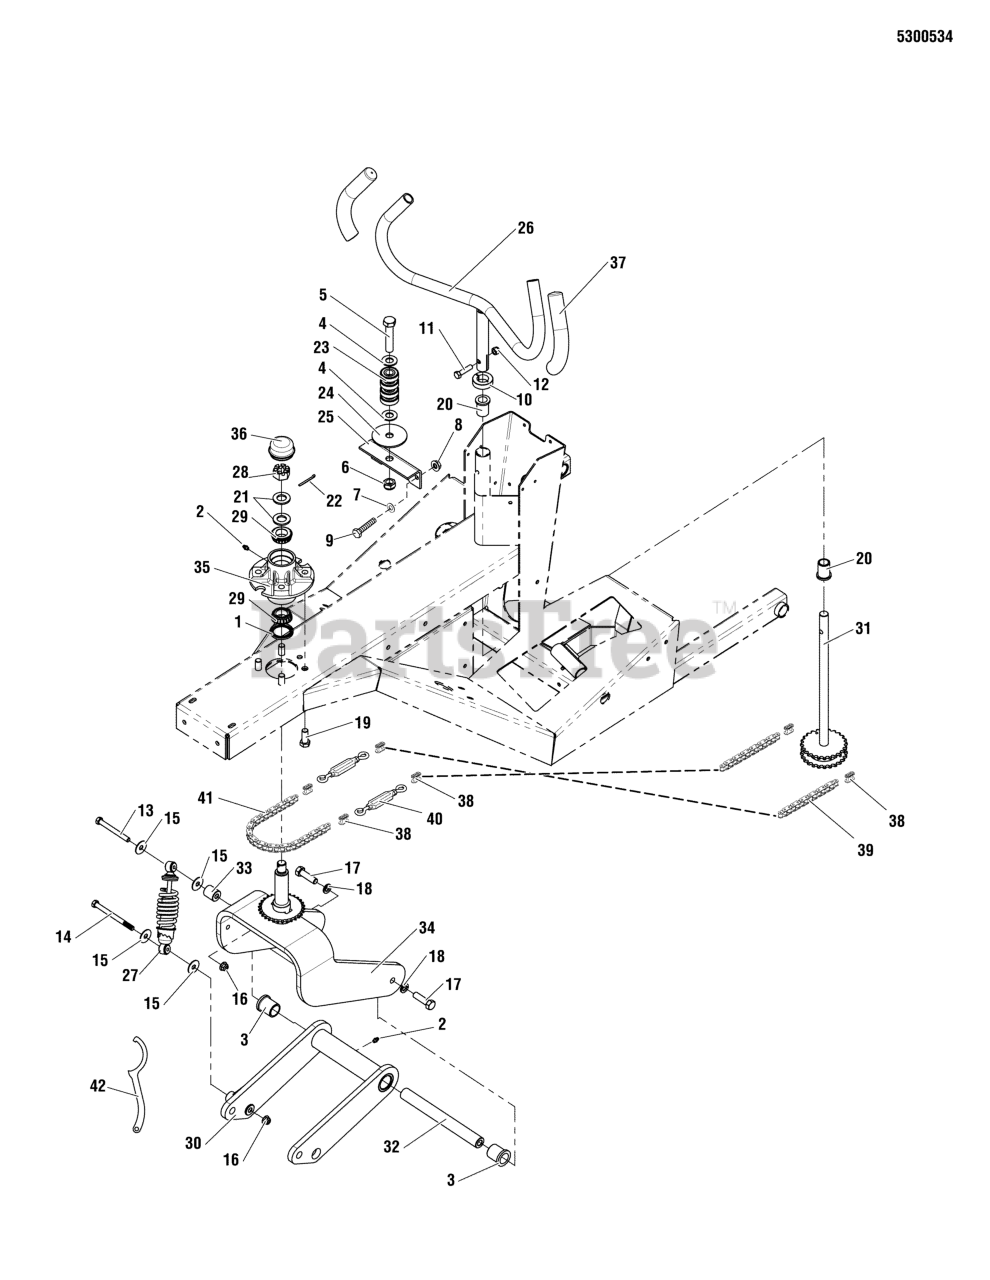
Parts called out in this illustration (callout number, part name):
1	SEAL, 1.983" X 1.500 X .188
2	GREASE FITTING, 1/4-28 STRAIGHT
3	BUSHING, FLANGE
4	WASHER, 5/8" SAE
5	BOLT, 5/8-11 x 3" GD5 CZ
6	NUT, 5/8-11 HEX JAM NYLON LOCK
7	WASHER, 5/16" SAE
8	NUT, 5/16-18 HEX NYLOCK FLANGE
9	BOLT, 5/16-18 X 3/4 GD5
10	COLLAR, 1" SPLIT
11	BOLT, 3/8-16 X 1-1/2" GD5 CZ
12	NUT, 3/8-16 HEX NYLON LOCK
13	BOLT, 3/8-16 X 3-1/2" GD5 CZ
14	BOLT, 3/8-16 X 4-1/2" GD5 CZ
15	WASHER, 3/8" FENDER
16	NUT, 3/8-16 HEX NYLOCK FLANGE
17	BOLT, 1/2-20 X 1-3/4" GD8 CZ
18	WASHER, 1/2" SPLIT LOCK
19	BOLT, 1/2-20 X 1-1/4" GD5 CZ
20	BUSHING, FLANGE, 3/4 X 1
21	WASHER, 3/4 SAE
22	PIN, COTTER, 1/8 X 1-1/4
23	BEARING, ROLLER, 5/8" ID
24	WASHER, .64 X 3.00 X .14
25	MOUNT, CHAIN ROLLER
26	WELD, STEERING HANDLE - RED
27	SHOCK, SUSPENSION
28	NUT, 3/4-16 HEX SLOTTED
29	BEARING, TAPER ROLLER, 1.1417
30	WELD, SWING ARM - RED
31	STEERING SHAFT WELDMENT
32	SPACER, 1.00 X 9.32 - TAPPED
33	SPACER, .39 X 1.00 X 1.13
34	WELD, MOUNT, STEERING TIRE - RED
35	HUB ASSEMBLY
36	CAP, DUST
37	GRIP, FOAM 1" ID X 7.75" LONG
38	CHAIN,LINK CONNECTOR #40
39	#40 CHAIN 33 LINKS
40	ASSEMBLY, TURNBUCKLE
41	#40 CHAIN, 43 LINK
42	WRENCH, SPANNER, CZ
